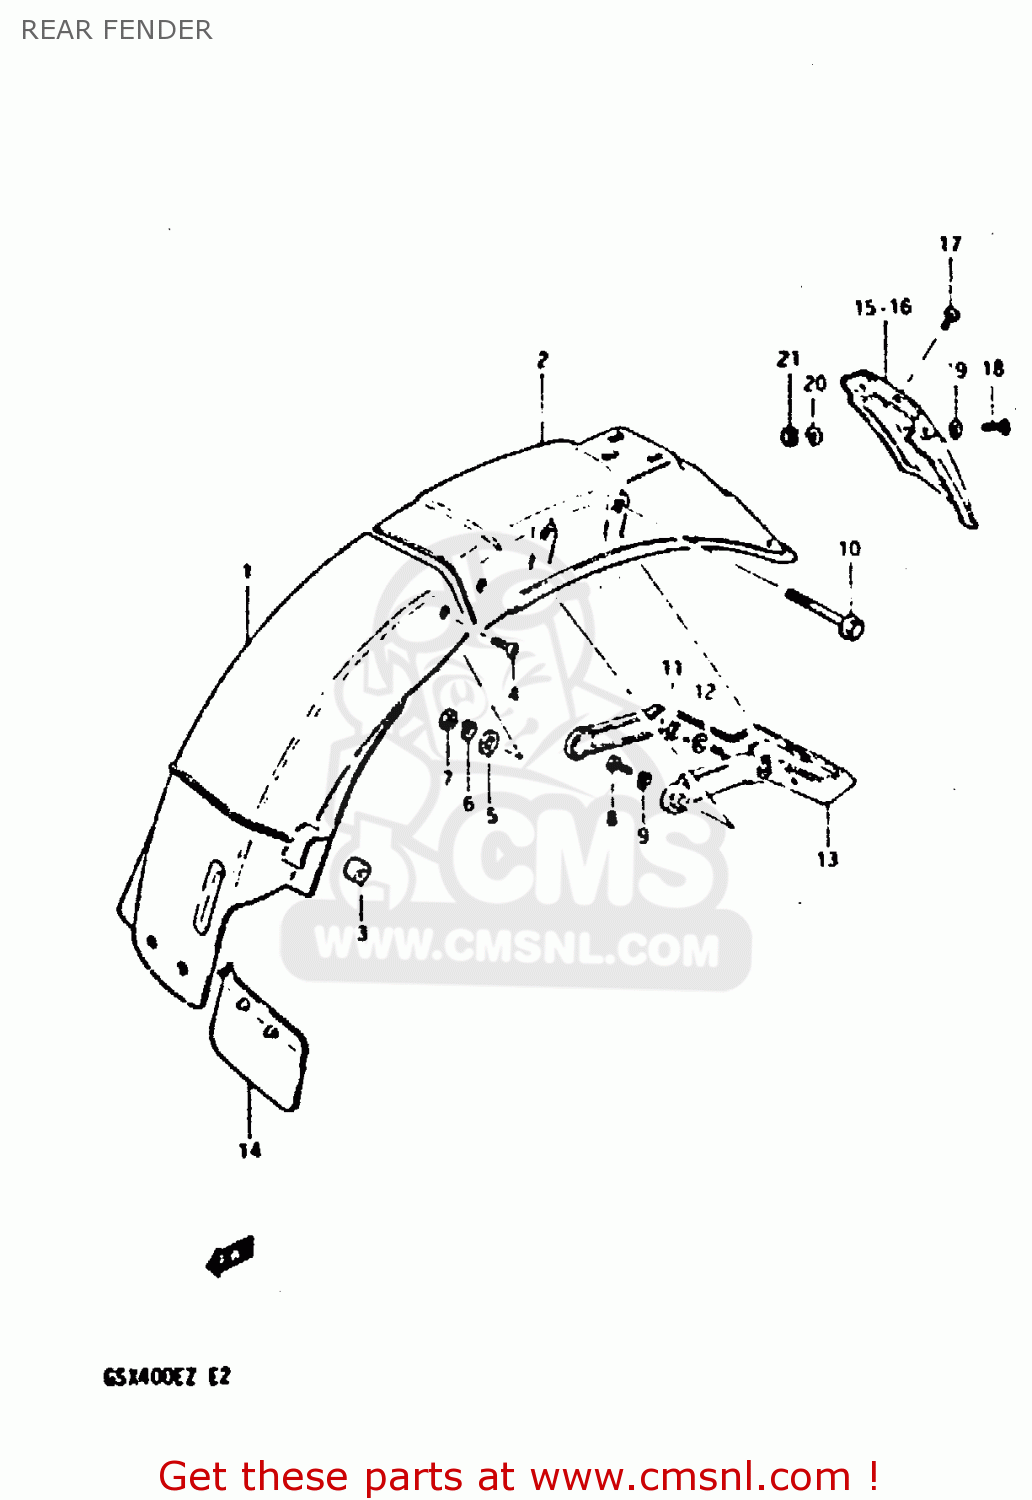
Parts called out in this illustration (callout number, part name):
1	FENDER,REAR
2	BODY,REAR FENDER,REAR
3	CUSHION
4	SCREW
5	WASHER (5.5X16X1.2)
6	LOCK WASHER
7	NUT
8	BOLT, UPPER
9	LOCK WASHER
10	BOLT
11	NUT
12	LOCK WASHER
13	REINFORCEMENT,REAR FENDER
14	GUIDE,RR FENDER MUD
